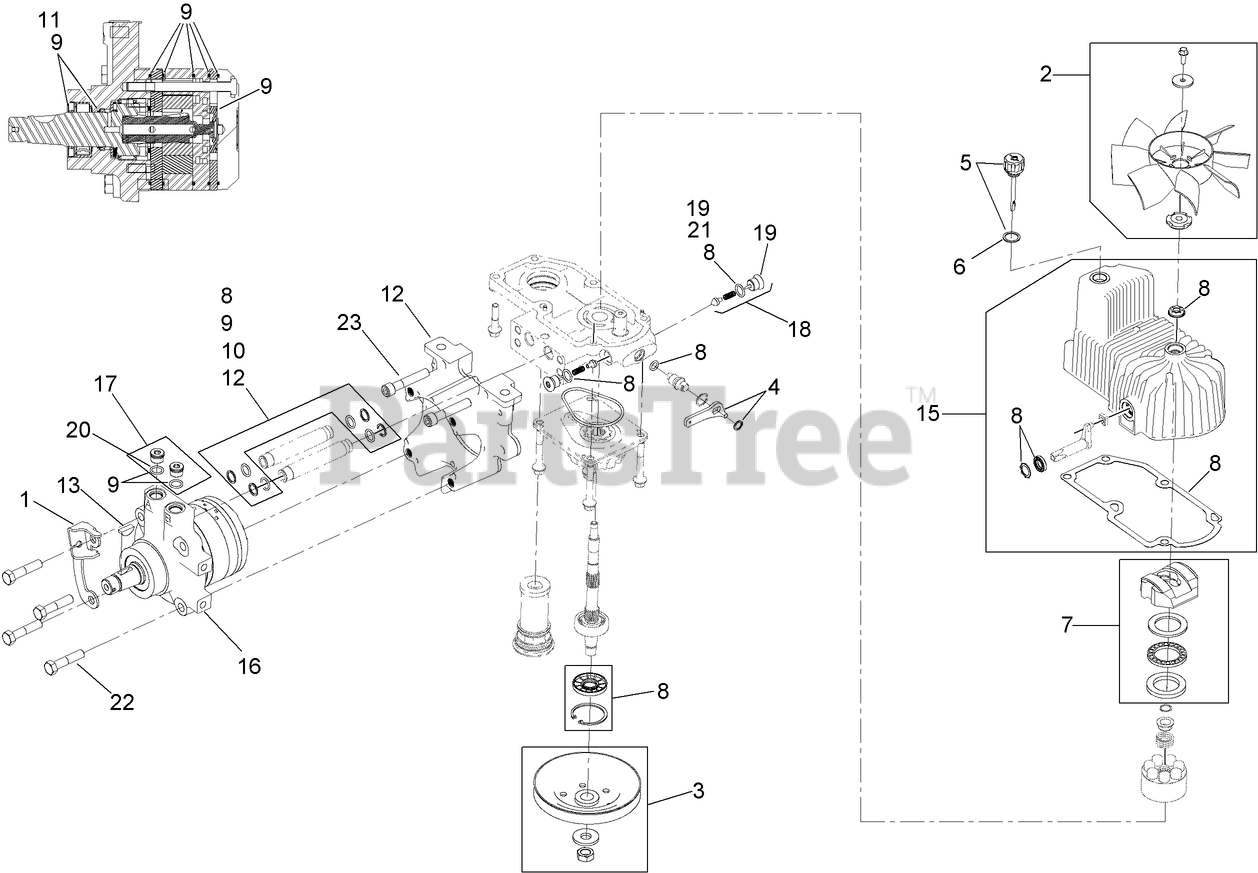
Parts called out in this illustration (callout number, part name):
1	BRACKET-ANCHOR, CABLE
2	FAN KIT
3	PULLEY KIT
4	HANDLE-BYPASS VALVE, HYDRO
5	DIPSTICK-HYDRO W/GASKET
6	GASKET-DIPSTICK, HYDRO
7	SWASH BLOCK KIT
8	PUMP SEAL KIT
9	MOTOR SEAL KIT
10	TUBE SEAL KIT
11	OUTPUT SHAFT SEAL KIT
12	NOSE CUP-UHT
13	Key-Woodruff 5/16 x 1
15	Housing-LH
16	MOTOR-HYDRAULIC LH 240CC
17	MAGNETIC PLUGS SERVICE KIT
18	CHECK VALVE ASM
19	PLUG-CHECK (W/O-RING)
20	O-RING
21	O-RING-CHECK VALVE
22	SCREW-HH 1/2-20 X 2 1/4
23	SCREW-HSH 1/2-20 X 2 3/4
